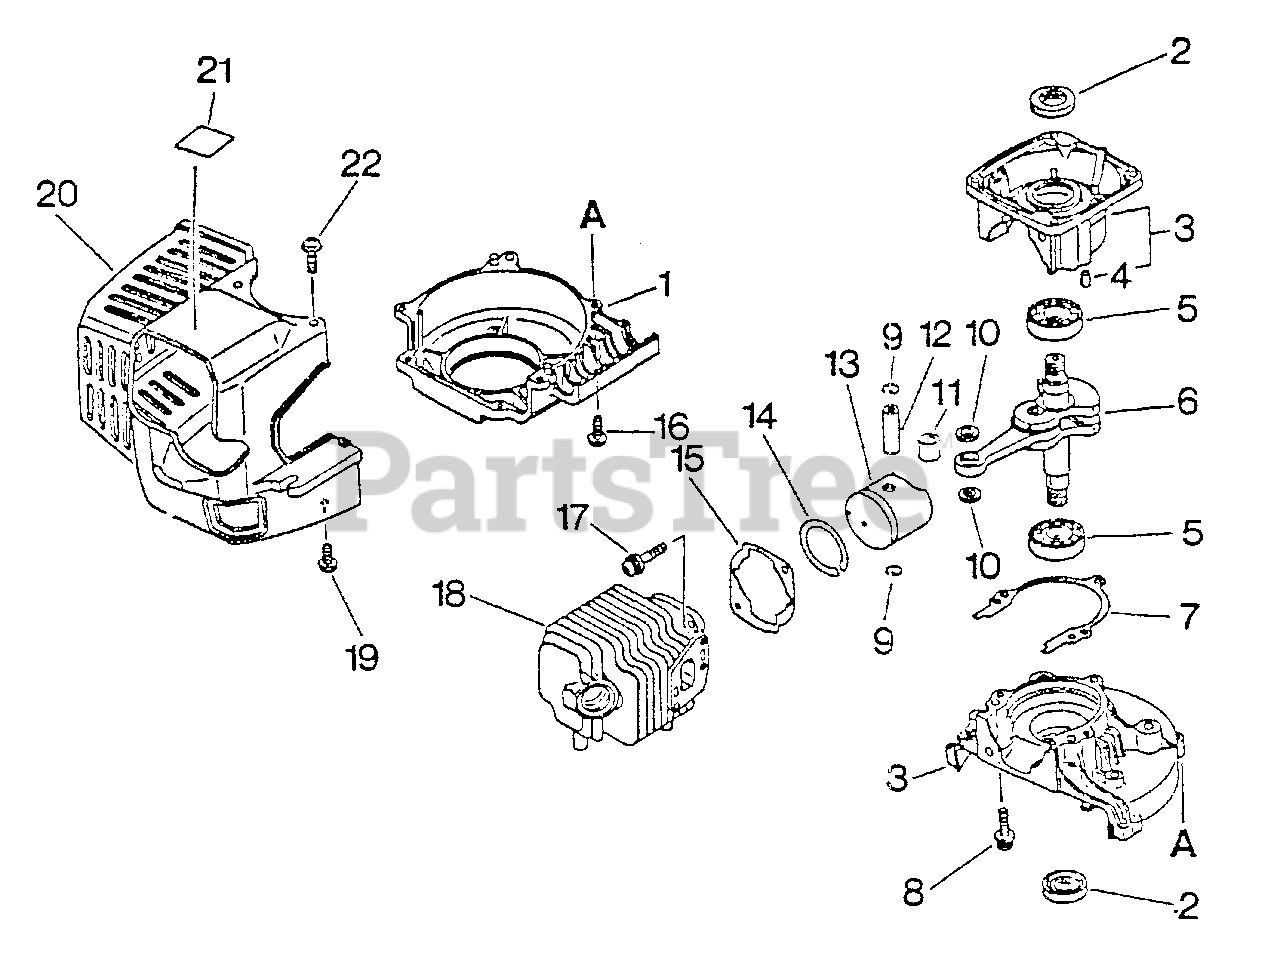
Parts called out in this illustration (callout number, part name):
1	CASE, FAN
2	SEAL, OIL
3	CRANKCASE KIT
4	PIN - LOCATING
5	BEARING, BALL - 6201
6	CRANKSHAFT ASSY
7	GASKET, CRANKCASE
8	SCREW - 5X28
9	RING, RETAINING
10	SPACER, PISTON
11	BEARING, NEEDLE
12	PIN, PISTON
13	PISTON
14	RING, PISTON
15	GASKET, CYLINDER
16	SCREW - 4X14
17	SCREW - 5X22
18	CYLINDER
19	SCREW - 4X16
20	COVER, ENGINE - GRAY
21	LABEL - MODEL
22	SCREW - 4X12
